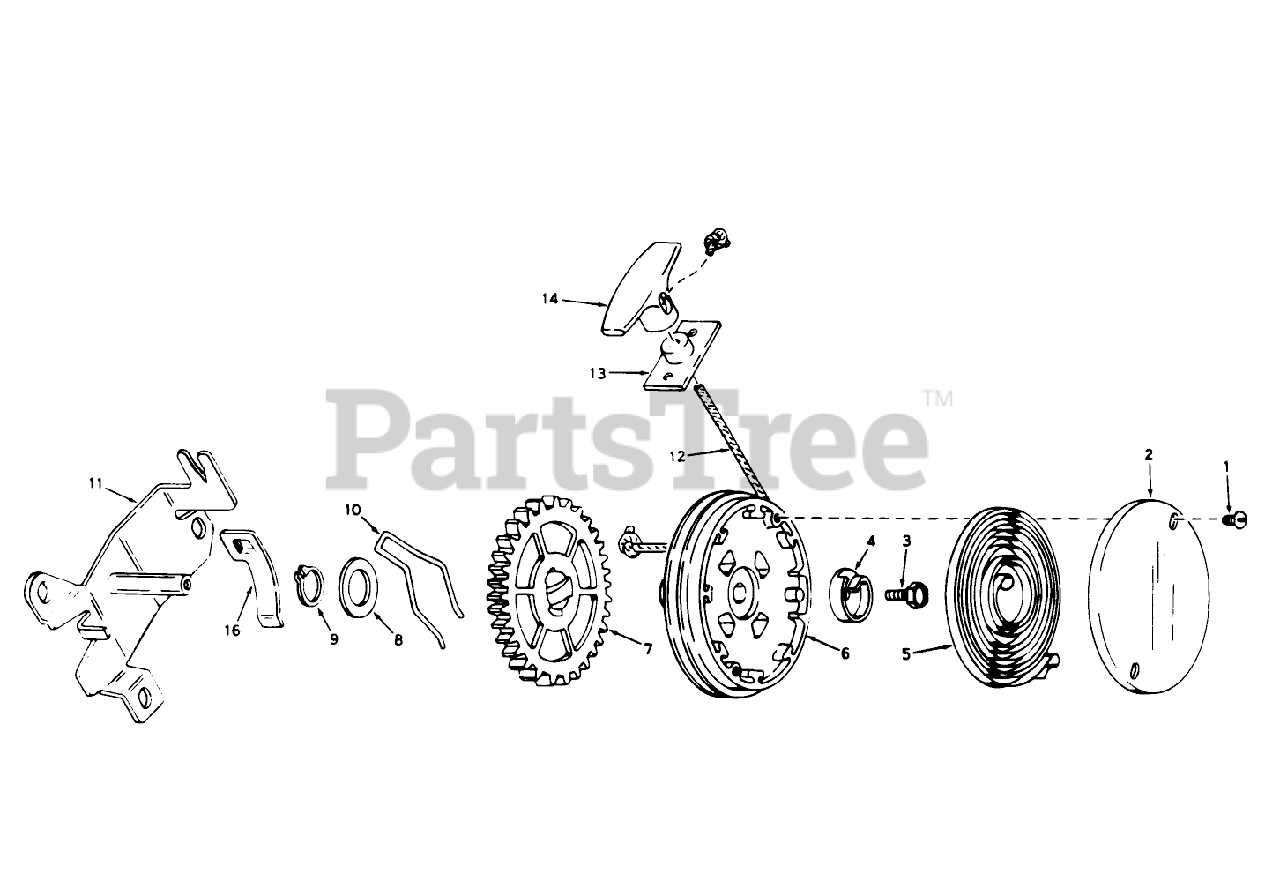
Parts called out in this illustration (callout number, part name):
1	Screw, Cover
2	Cover, Spring
4	Hub Spring
5	Spring, Rewind
6	Pulley
7	Gear
8	Washer
9	Ring, Snap
11	Bracket Assy. Mounting
12	Rope, Starter
13	Bracket Assy.
14	Handle-Starter
16	Clip Rope
